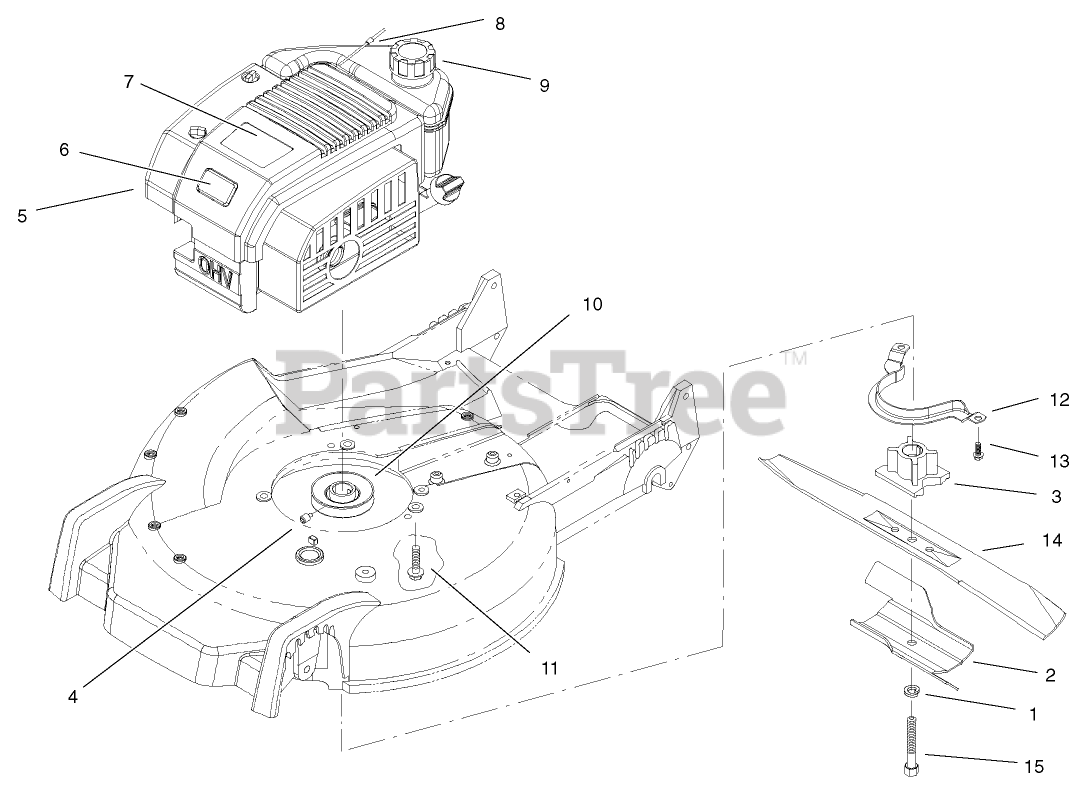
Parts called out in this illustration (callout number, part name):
1	WASHER-LOCK
2	ACCELERATOR-BLADE
3	RETAINER-BLADE
6	DECAL
7	DECAL - RECOIL
8	STOP-ROPE
9	GAS CAP ASM
10	PULLEY ASM
11	SCREW-HWH
13	SCREW-HWHTF
